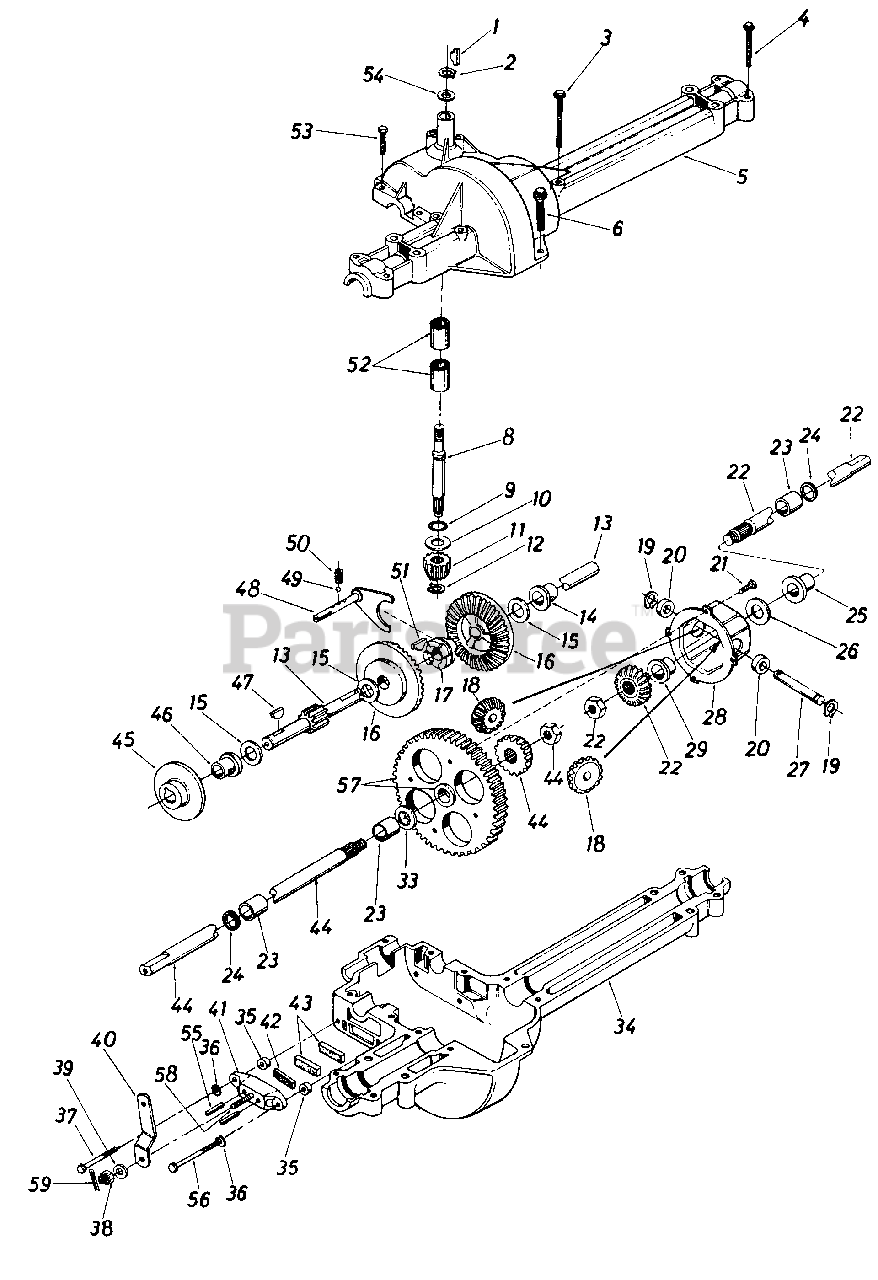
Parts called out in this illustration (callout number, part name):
1	#4 Hi-Pro Key 3/32 x 5/8" Dia.
2	Snap Ring .625" Shaft
3	Hex Bolt 1/4-20 x 1.75" Lg.
4	Hex Tap Scr. 1/4-20 x 1.25" Lg.
5	Upper Housing
6	Hex TT-Tap Scr. 1/4-20 x .75" Lg.
8	Input Shaft
9	Square Seal 5/8" I.D.
10	Thrust Washer 5/8" I.D. x 1 25" O.D.
11	Pinion Input 14T
12	Retaining Ring 7/16" Ext.
13	Drive Shaft
14	Flange Brg. 5/8" I.D. x 3/4" Lg.*
15	Fl-Wash.
16	Bevel Gear 42T
17	Clutch Collar
18	Miter Gear 1 5T (H.D.)
19	Retainer Ring
20	Thrust Bearing
21	Pan Head Scr. 1/4-20 x .50" Lg. w/Patch
22	Axle R.H. Ass'y.
23	Sleeve Bearing 3/4" I.D. x 1.0" Lg.
24	Oil Seal 3/4" I.D.
25	Flange Bearing 3/4" I.D. x 15/16" Lg.
26	Fl-Wash. .760" I.D. x 1.5" O.D.
27	Cross Shaft
28	Differential Housing Ass'y.
33	Fl-Wash. .760" I.D. x 1.5" O.D.
34	Lower Housing
35	Spacer .53" O.D. x 3/8" Lg.
36	L-Wash. 1/4" I.D.
37	Hex Bolt 1/4-20 x 1.50" Lg. (Grade 5)
38	Castle Nut 5/16-24 Thd.
39	Fl-Wash. .344" I.D. x .875" O.D.
40	Actuating Arm
41	Brake Yoke
42	Puck Plate
43	Brake Puck
44	Axle L.H. Ass'y.
45	Brake Disc
46	Flange Bearing 5/8" I.D. x 15/16" Lg.
47	Woodruff Key 3/16 x 5/8 HT
48	Shift Fork Ass'y.
49	Ball Detent .250" Dia.
50	Spring Detent
51	#9 Hi-Pro Key 3/16" x 3/4" Dia. HT
52	Needle Brg. 5/8" I.D. x 1/2" Lg.
53	Hex Bolt 1/4-20 x 1.00" Lg.
54	Fl-Wash. 5/8" I.D. x .030
55	Actuating Pin 5/16" Dia.
56	Hex Bolt 1/4-20 x 2.50" Lg. (Grade 5)
57	Differential Gear 72T Ass'y. w/ Bearing
58	Sq. Hd. Bolt 5/16-24 Thd.
59	Cotter Pin 3/32" Dia. x 1.0" Lg.
